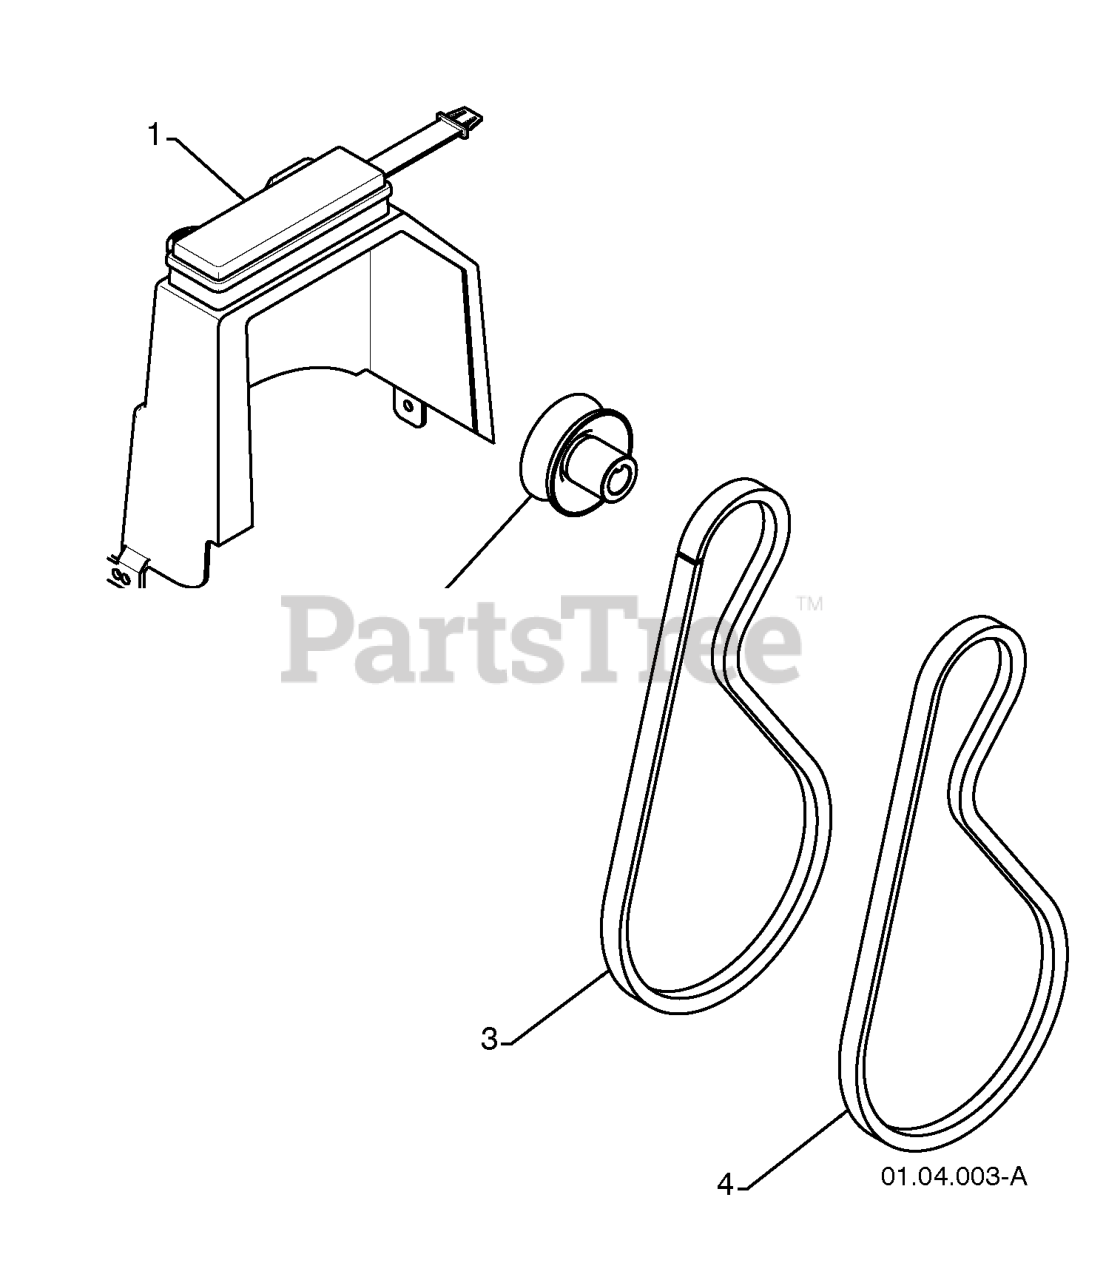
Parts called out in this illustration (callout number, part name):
1	COVER.ASM.BELT/STORAGE
2	PULLEY, ENGINE IMPELLER DRIVE
3	V-BELT TRACTION 34.25
4	BELT.V.IMPELLER
